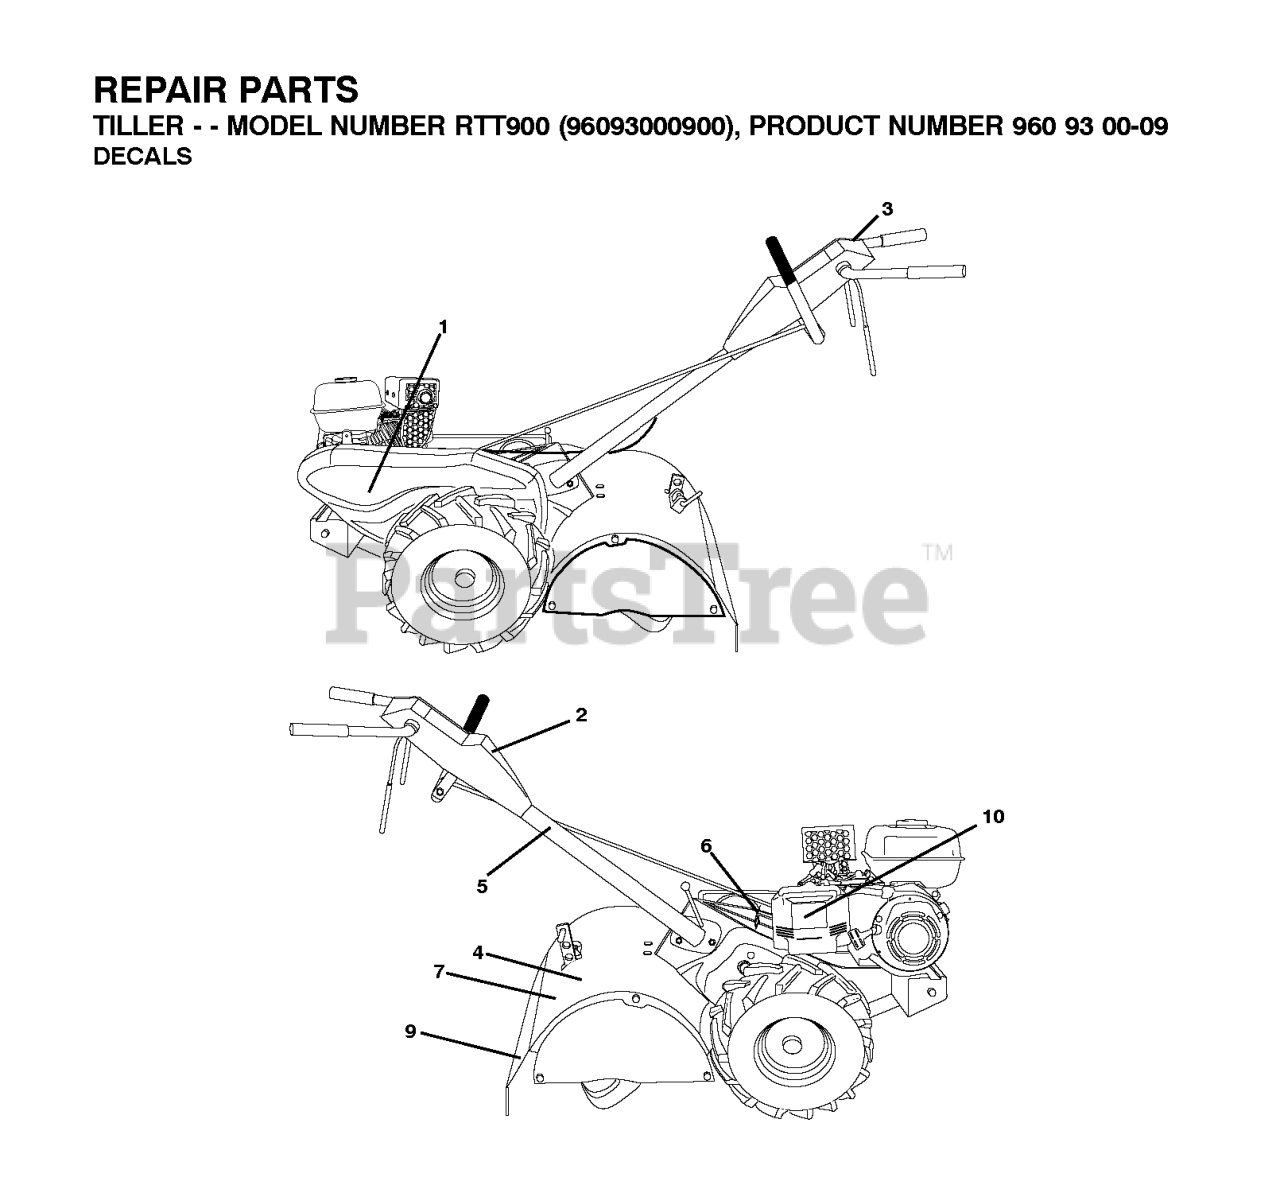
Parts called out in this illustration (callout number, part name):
1	DECAL.HOOD.LOGO.ORANGE.HUSQVAR
2	DECAL.CONSOLE.RTT900.
4	DECAL.SHIELD
5	DECAL TI (2 2)
6	DECAL.SHIFT.INDICATOR.TILLER
7	DECAL.WARNING.SHLD.ENG/FR
9	DECAL TI
